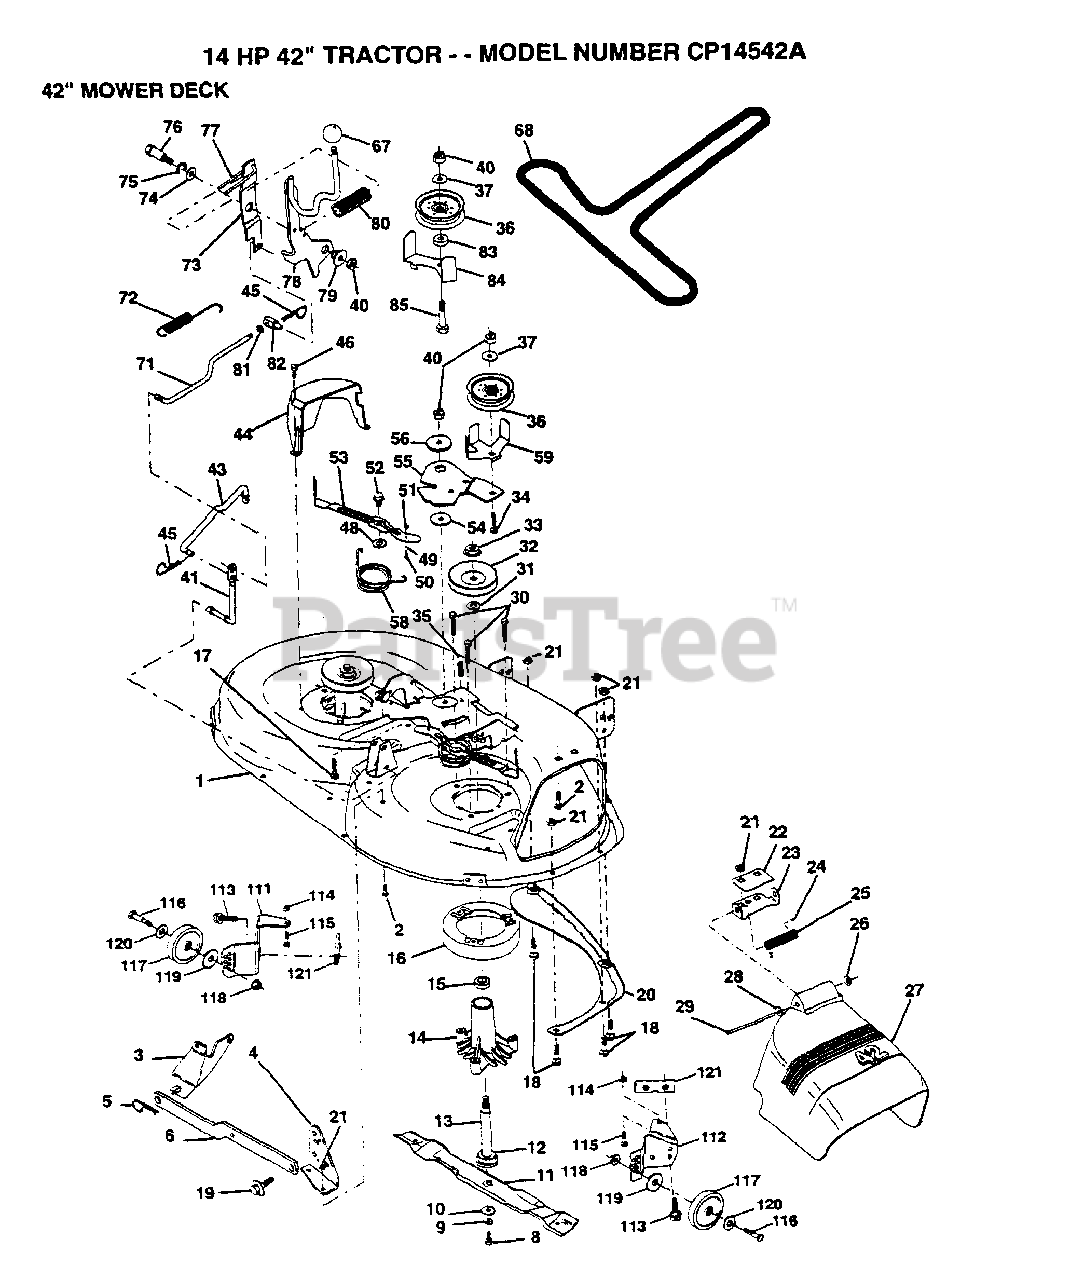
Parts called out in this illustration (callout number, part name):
1	DECK.WELD.42.
2	BOLT
3	BRKT ASM SWAY BAR
4	BRKT DECK SW BAR
8	BLADE BOLT
10	WASHER.HARD.BLADE
11	"BLADE.42"" HIPERF"
12	BEARING.BALL
14	HSG ASM MANDREL
15	BEARING
16	STRIPPER RND MWR
17	BOLT RDHD 3/8-16
18	BOLT
19	BOLT SHD 5/16-18
22	STIFFENER BRKT
23	DEFLECTOR BRKT
24	CAP-SLEEVE LT
25	SPRING TORSION
26	NUT PUSH M
27	DEFLECTOR.SHIELD
28	WASHER
29	HINGE ROD
31	WASHER
34	BOLT
35	XMAS TREE FASTNER
36	FLAT IDLER PULLEY
37	WASHER
41	PIVOT ROD
43	ROD CLUTCH W/NIBS
44	GUARD MAND LH BLK
45	RETAINER M
46	SCREW.1/4-20X5/8
48	HARD SMALL WASHER
50	SHOULDER BOLT
51	LOCKNUT
52	BOLT.SHLD.5/16-18
53	BRAKE PAD ARM ASM
54	HARDENED WASHER
56	SPACER RETAINER
58	SPRING TORSN BRAK
59	GUARD IDLER TUV
67	KNOB T (1/2-HOLE)
68	BELT.V.T-PATH
71	ROD CLUTCH 38/42
72	RETURN SPRING
73	CLUTCH ARM SECOND
74	WASHER
75	RING
76	SHOULDER BOLT
77	SPRING KEEPER
78	LEVER ASM CLT PRM
79	BUSHING
81	NUT
82	TRUNION ADJ
83	WASHER
85	BOLT
113	SCREW
116	BOLT M
117	WHEEL.GAGE.BLK.PL
118	LOCKNUT
119	WASHER
120	WASHER
121	BRACKET.EXTRD.GWL
